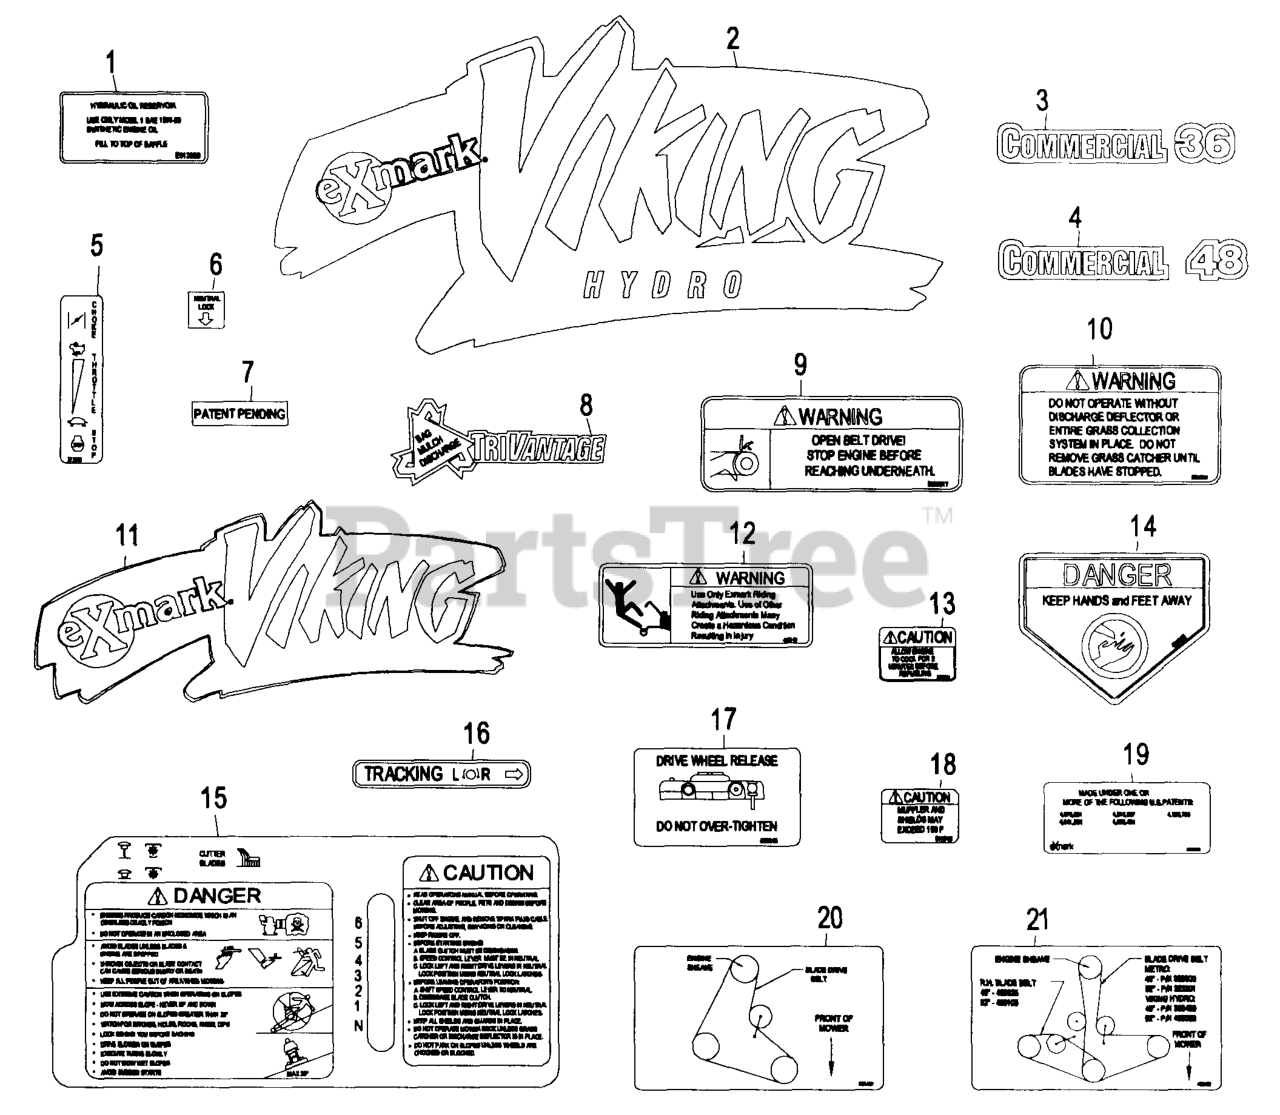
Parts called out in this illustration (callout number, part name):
1	DECAL,HYD TANK
3	DECAL,COMMERCIAL 36
4	DECAL,COMMERCIAL 48
6	DECAL,NEUTRAL LOCK
7	Decal, Patent Pending
9	DECAL,BELT DRIVE
10	DECAL-WARNING, DISCHARGE
12	DECAL,SULKY WARNING
14	DECAL-DANGER
16	DECAL,TRACKING ADJUST
17	DECAL,DRIVE RELEASE
20	DECAL,BELT ROUTING 32/36
